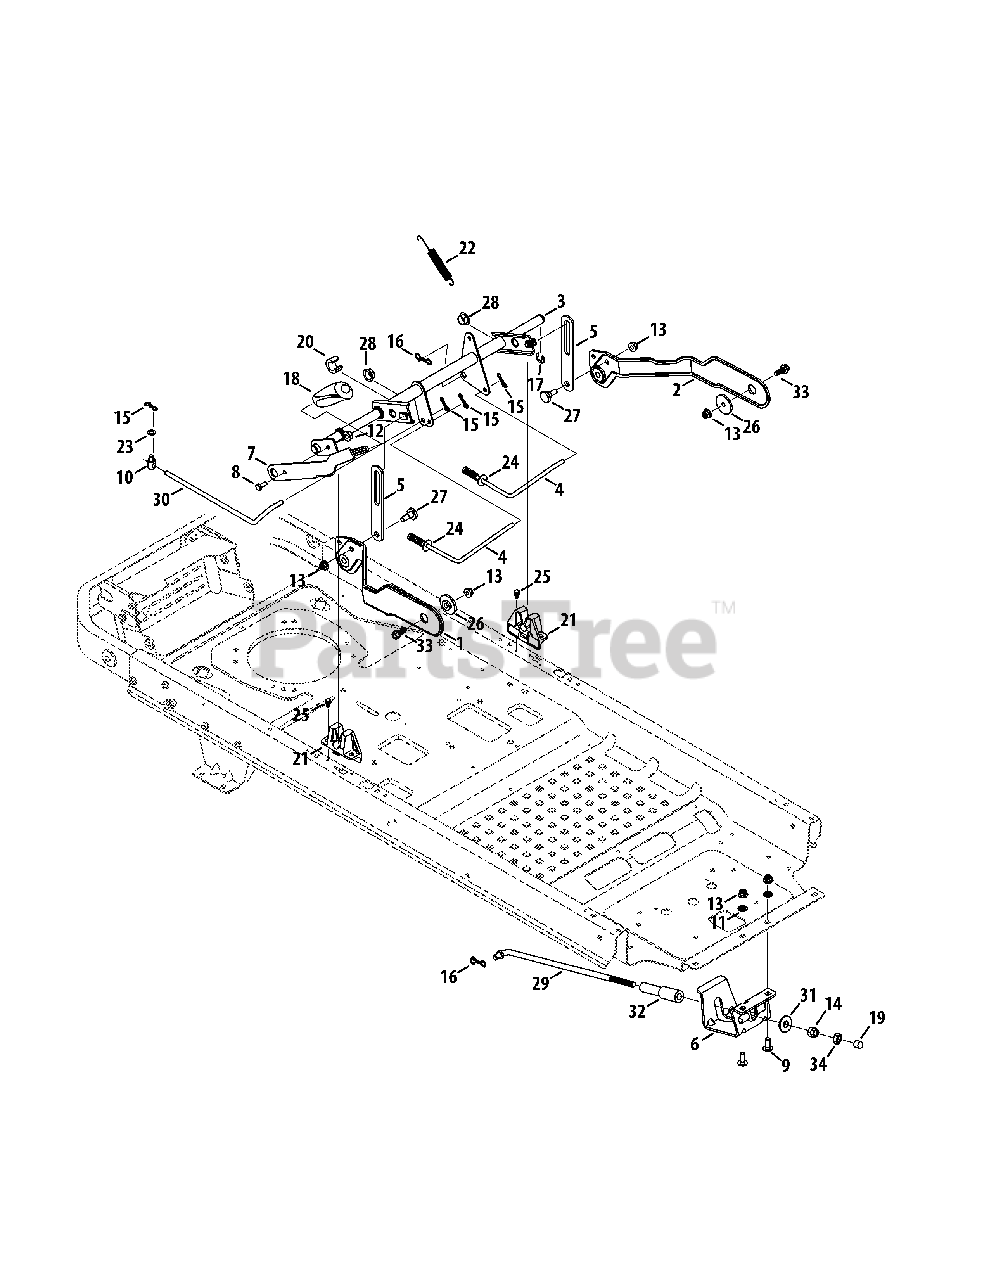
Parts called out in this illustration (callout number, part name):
1	Deck Lift Plate, RH
2	Deck Lift Plate, LH
3	Deck Lift Shift Assembly
4	Brake Rod Assembly
5	Lift Link Plate
6	Rod Support Mounting Bracket
7	Deck Lift Handle
8	Hex Cap Screw, 5/16-18 x .75
9	Carriage Bolt, 3/8-16 x 1.00
10	Ferrule, 3/8-24 x .375
11	Push Nut, 3/8
12	Flange Lock Nut, 5/16-18
13	Flange Lock Nut, 3/8-16
14	Hex Nut, 1/2-13
15	Bow-Tie Cotter Pin
16	Bow-Tie Cotter Pin
17	E-Type Ring, .750
18	Grip, .50 ID
20	Spacer, .76 ID x .750 LG
21	Deck Lift Bracket
22	Extension Spring, .63 Dia. x 4.95 LG
23	Washer, .375 x .700 x .030
24	Flat Washer, .344 x 1.00 x .063
25	Shoulder Screw, .500 x 1/4-20
26	Shoulder Spacer, .854 x .232
27	Shoulder Screw, .500 Dia. x .434
28	Flange Bearing, .751 x 1.125 x .375
29	Deck Lift Rod
31	Deck Lift pivot Cup
32	Nylon Sleeve, .55 ID x 4.50 LG
33	Screw, 3/8-16 x 1.00
34	Jam Nut, 1/2-13
